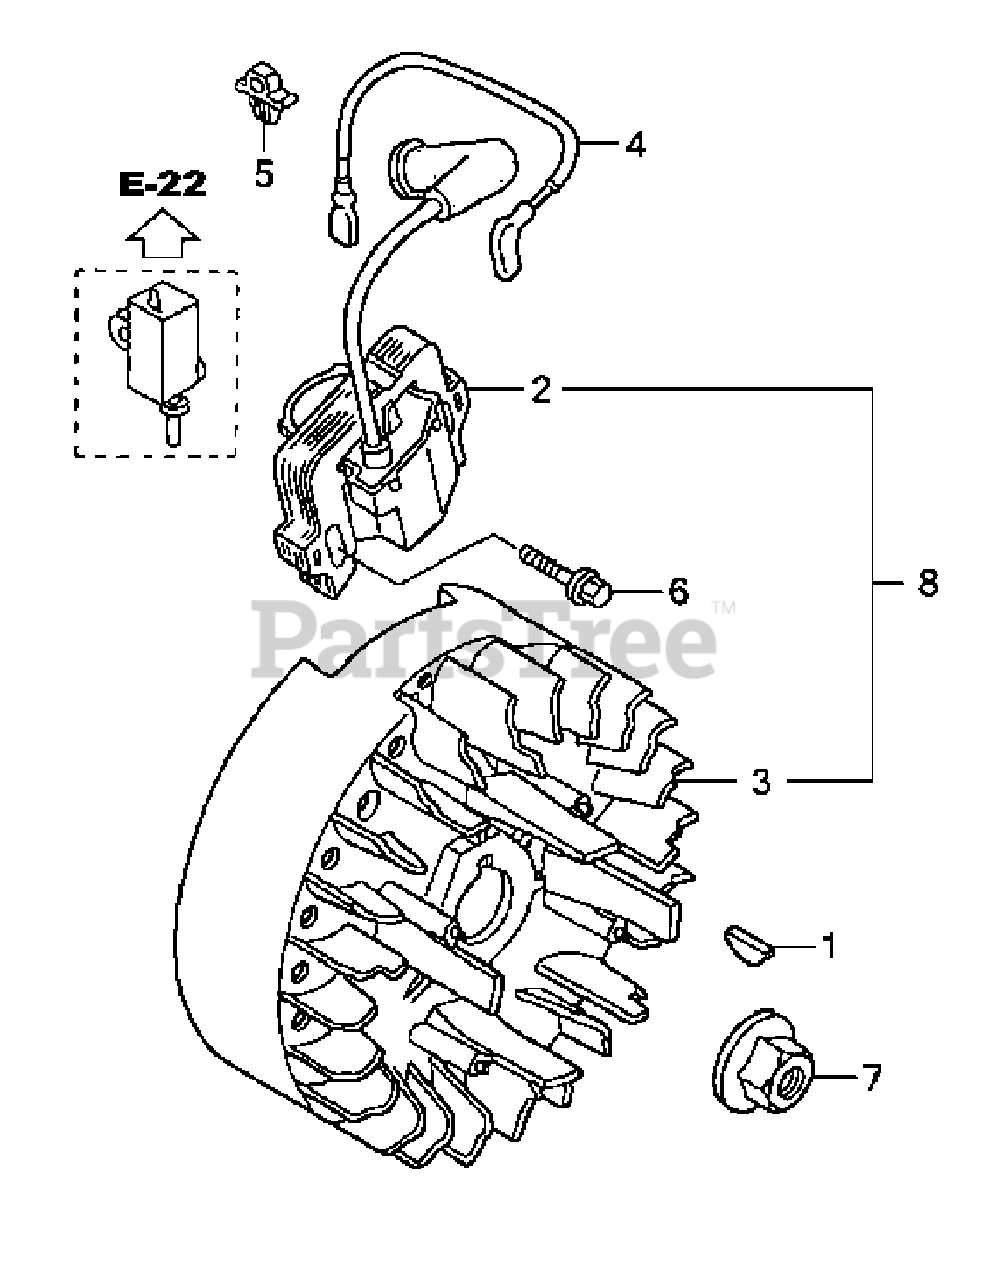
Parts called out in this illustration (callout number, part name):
1	Key, Special Woodruff, 25X18
2	Coil Assy., Ignition (Phelon)
3	Flywheel (Phelon)
4	Cord, Stop Switch
5	Holder, Stop Switch Cord
5	Holder, Wire (Fastex)
6	Bolt, Flange, 6X20 (Ct200)
7	Nut, Flange, 14Mm
